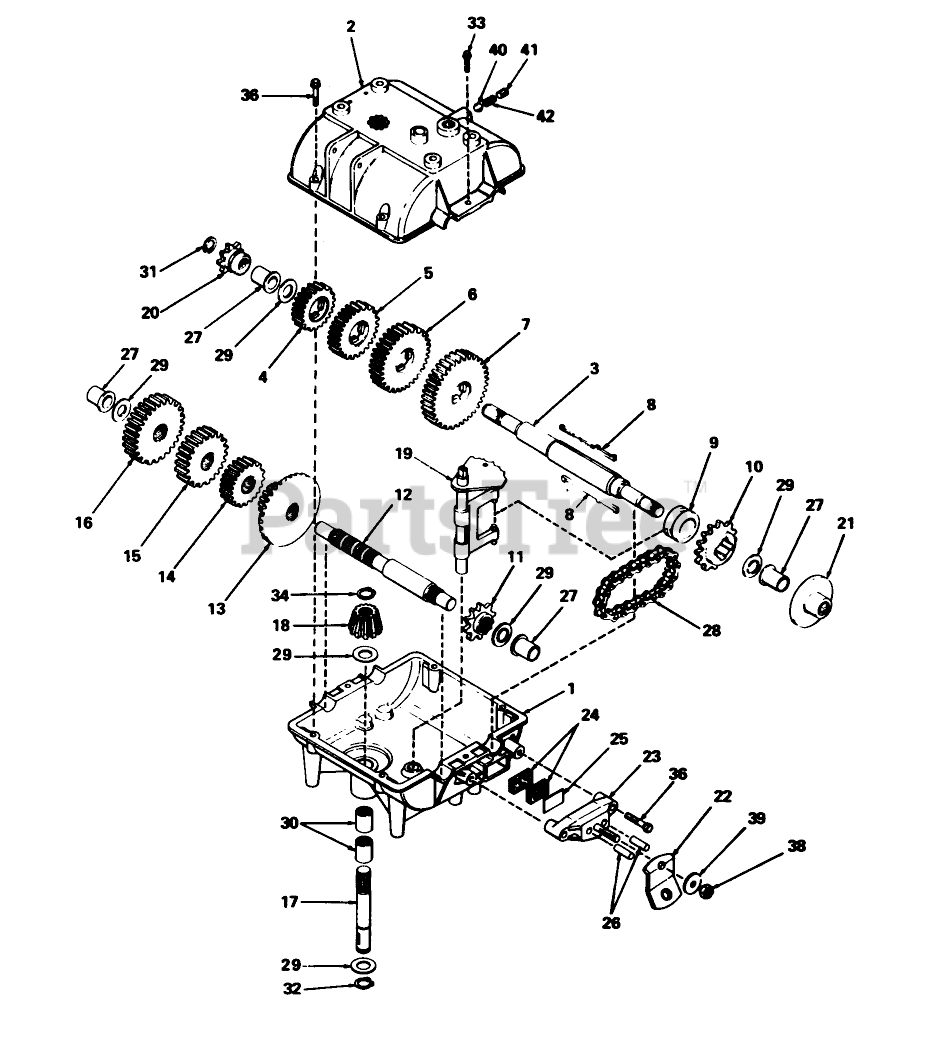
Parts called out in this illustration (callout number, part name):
1	Case-Transmission
2	Cover, Transmission
3	Shaft, Output Brake
4	Gear, Spur (20 Teeth)
5	Gear, Spur (25 Teeth)
6	Gear, Spur (30 Teeth)
7	Gear, Spur (35 Teeth)
9	Collar-Shift
10	Sprocket (14 Teeth)
11	Sprocket 10t
12	Countershaft
13	Gear-Bevel (42 tooth 15 tooth spur gear)
14	Gear, Spur (20 Teeth)
15	Gear, Spur (25 Teeth)
16	Gear, Spur (30 teeth)
17	Shaft-Input
18	Bevel Pinion, Input
19	Rod Fork Assy, Shifter
20	Sprocket (8Teeth)
22	Lever, Brake
23	Holder-Brake Pad
24	Brake Pad
25	Brake Pad Plate
26	Dowel Pin
27	Bushing, Flanged
28	Chain, Roller (#41 Chain, 22 Links)
29	Washer
30	Bearing, Needle
31	Piston Asm (.020 O S)
32	Ring-Snap
33	Screw, Hex Hd. Tap-Tite
34	Ring-Retainer
36	Ring Set (.020 O S)
38	Locknut
39	Washer
40	Ball-Steel
41	Screw-Set
42	Spring
